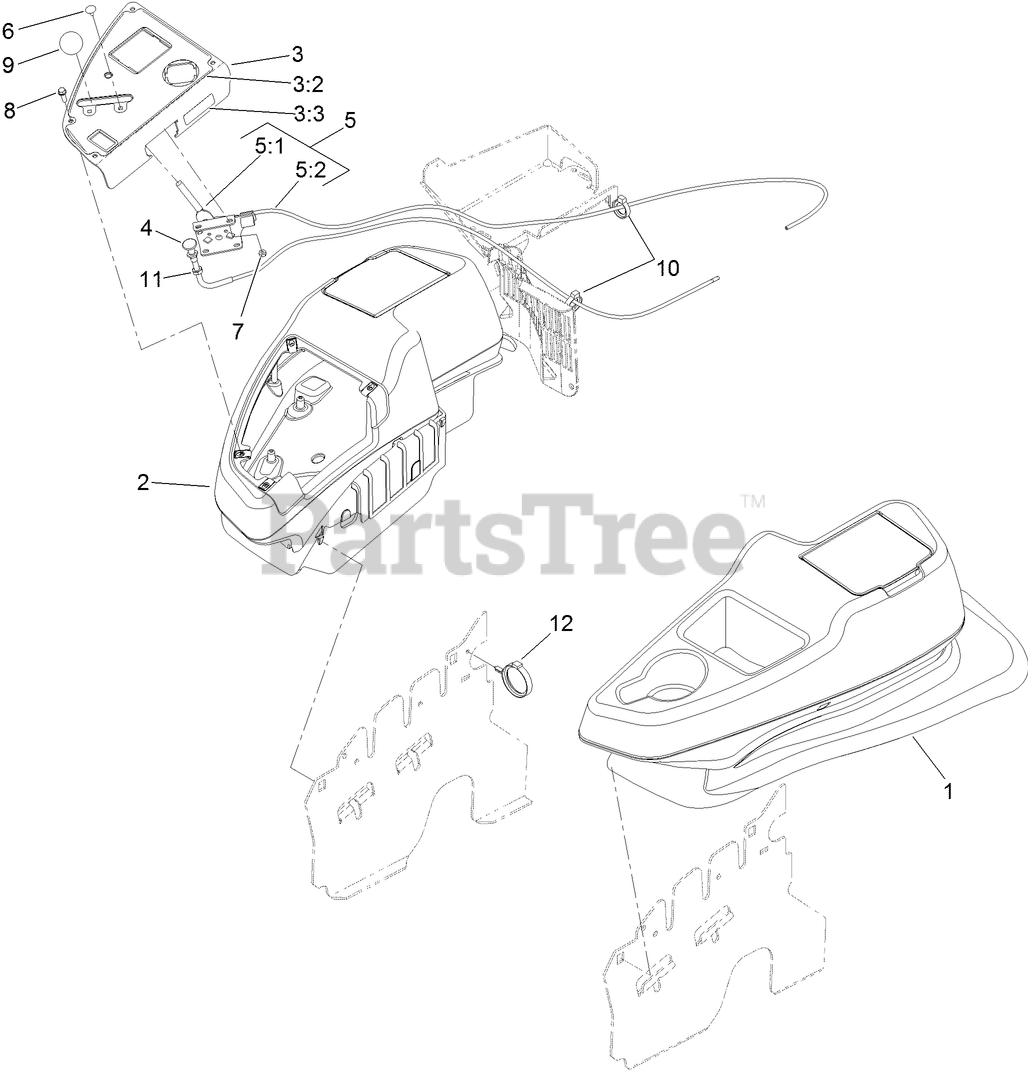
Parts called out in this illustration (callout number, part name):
1	LH CONSOLE ASM
2	RH CONSOLE ASM
3	CONTROL PANEL ASM
3:2	DECAL-PANEL, CONTROL
3:3	DECAL-FUSES
4	CHOKE CONTROL ASM
5	THROTTLE CONTROL ASM
5:1	LEVER-THROTTLE
5:2	CABLE-THROTTLE
6	BOLT-CARR
7	NUT-LOCK, NI
8	SCREW-HWH
9	KNOB-BALL
10	CLAMP-HOSE
11	NUT-HJ
12	CLAMP-HARNESS
